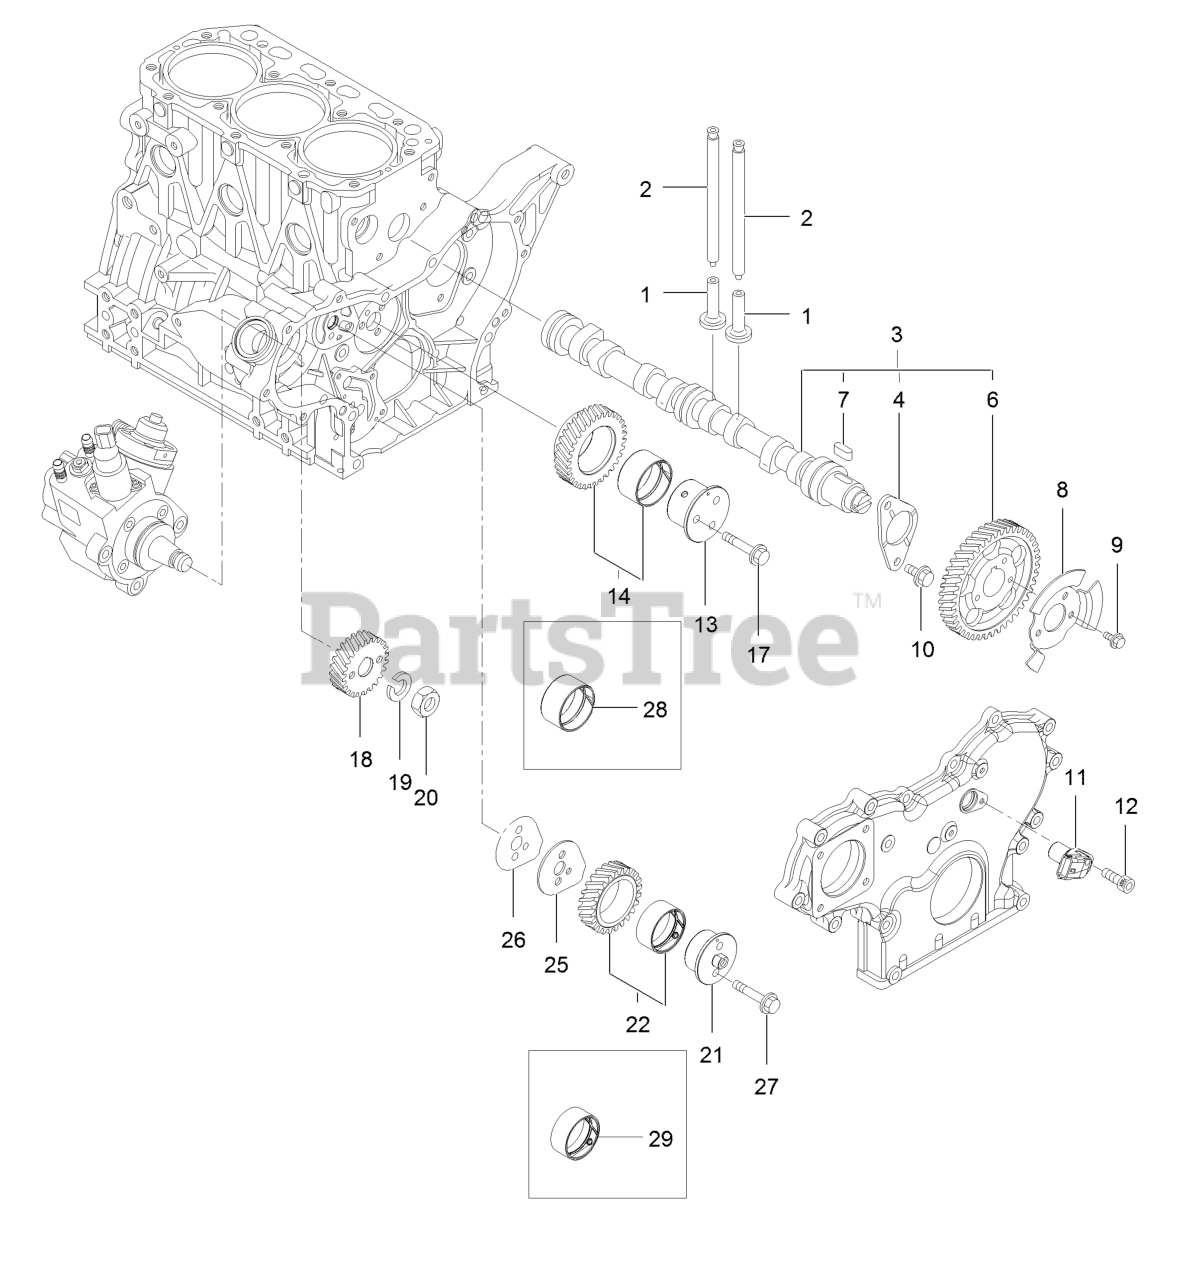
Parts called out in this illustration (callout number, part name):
2	Rod-Push
3	Camshaft ASM
4	Metal-Thrust
7	Gear-Camshaft
8	Pulser-Camshaft
11	Sensor-Rev, Gear
13	Shaft-Idle, Gear A
14	Idle Gear A ASM
18	Gear-Pump, Supply
19	Washer-Spring
20	Nut-Lock
21	Shaft-Idle, Gear B
22	Idle Gear B ASM
25	Plate-Idle, Shaft
26	Gasket-Idle, Shaft B
28	Bushing
29	Bushing
